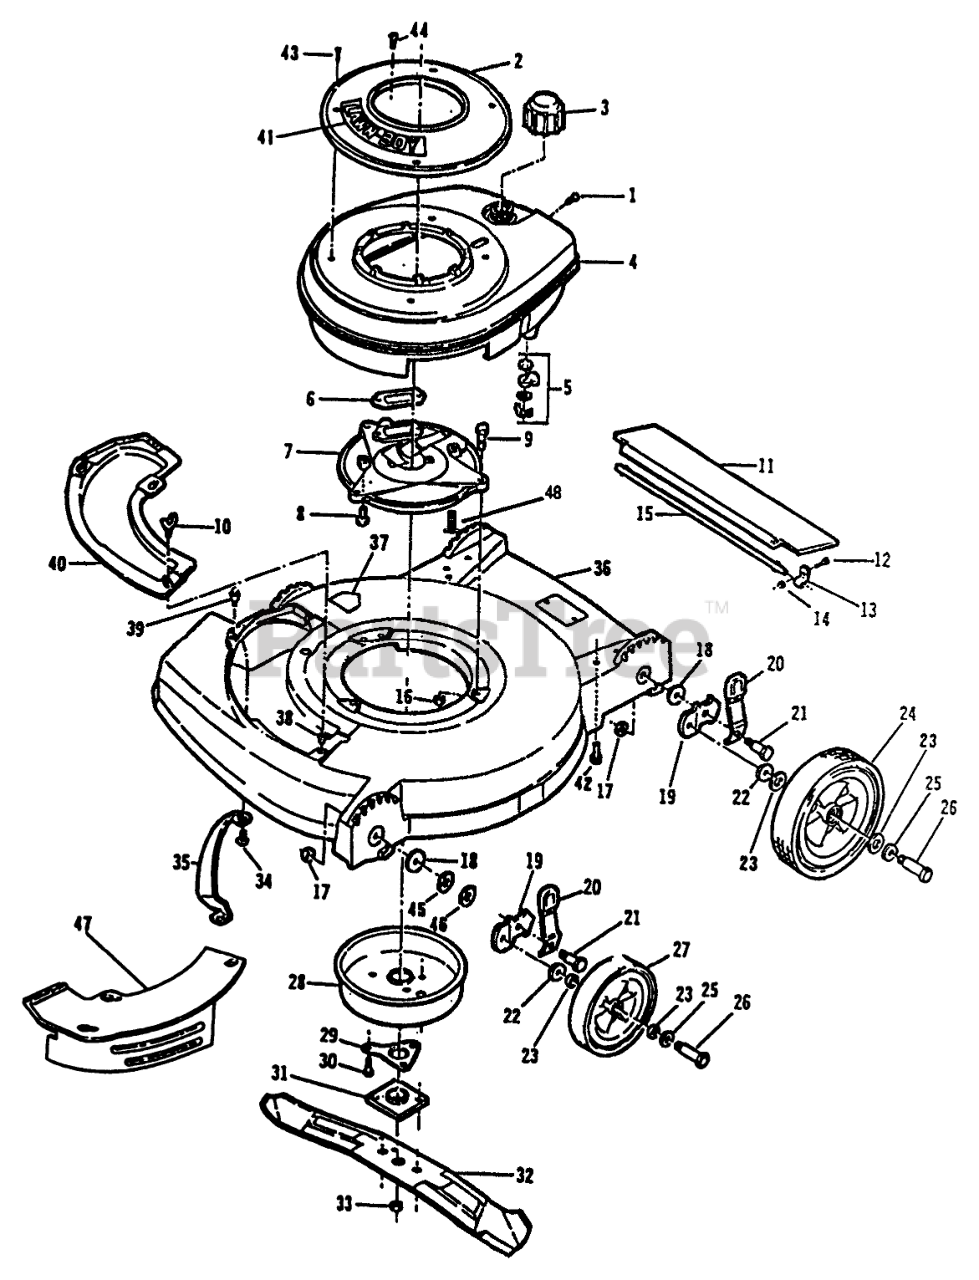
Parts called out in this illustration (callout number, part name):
1	SCREW S
2	STARTER BASE&NUTB
3	FUEL CAP & INSERT
4	Shroud-Engine
5	SHUT OFF VALVE KIT
6	Gasket
7	PLATE F
8	SCREW V
9	SCREW-HH
10	WING SCREW LAWRE
11	SHIELD
12	Screw
13	CLAMP ROD KMC
14	LOCKNUT E
15	ROD 21" ADVANCE
16	NUT-LOCK F
17	NUT
18	WASHER
19	Bracket
20	SPRING ARM ASM
21	BOLT
22	WASHER WROUGHT
23	WASHER
24	WHEEL&TIRE AY.
25	WASHER-PLAIN
26	BOLT WHEEL
27	Front Wheel
28	MUFFLER COVER F
29	SUPPORT F
30	SCREW
31	PLATE AND COLLAR ASM
32	21" Blade
33	NUT-BLADE
34	Screw
35	BAR-TOE
36	HSG AY-SERV-21"G
37	Decal
38	Grommet
39	Bolt
40	CoverPlate
41	APPLIQUE
42	SCREW
43	SCREW S
44	SCREW SEMS SM
45	WASHER
46	WASHER
47	Mulcher Plate Kit w/Decal
48	SCREW-SEMS F
